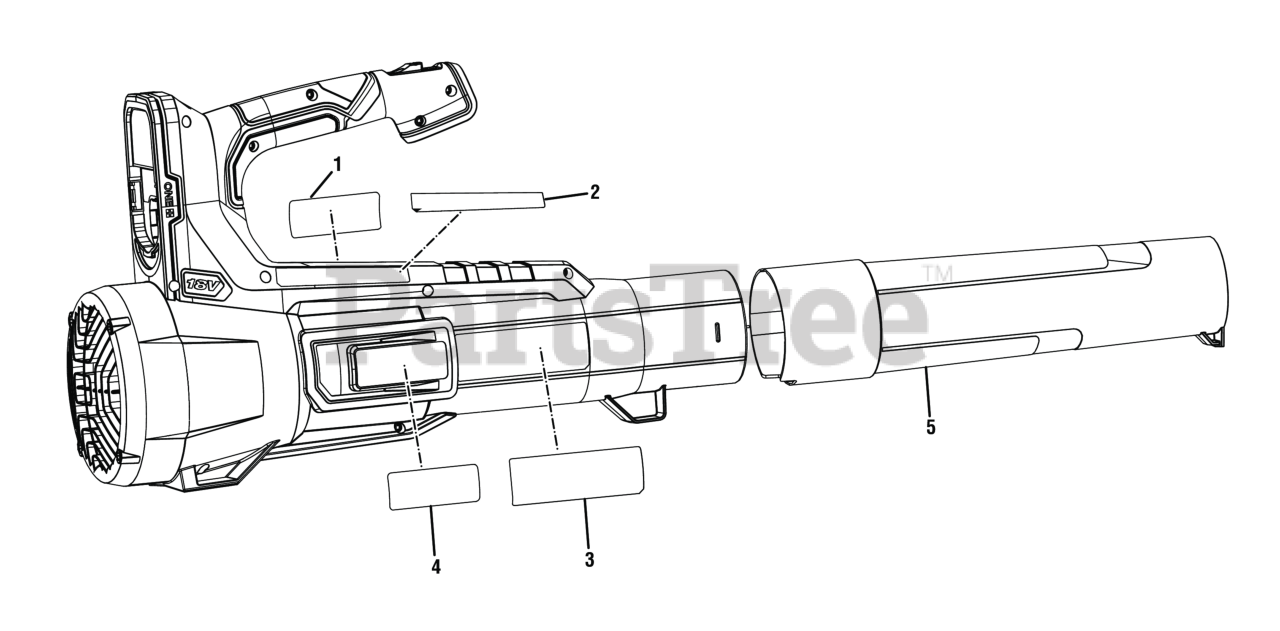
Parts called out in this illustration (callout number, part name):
1	Logo Label
2	Icon Label
3	Warning Label
4	Data Label
5	Blower Tube
